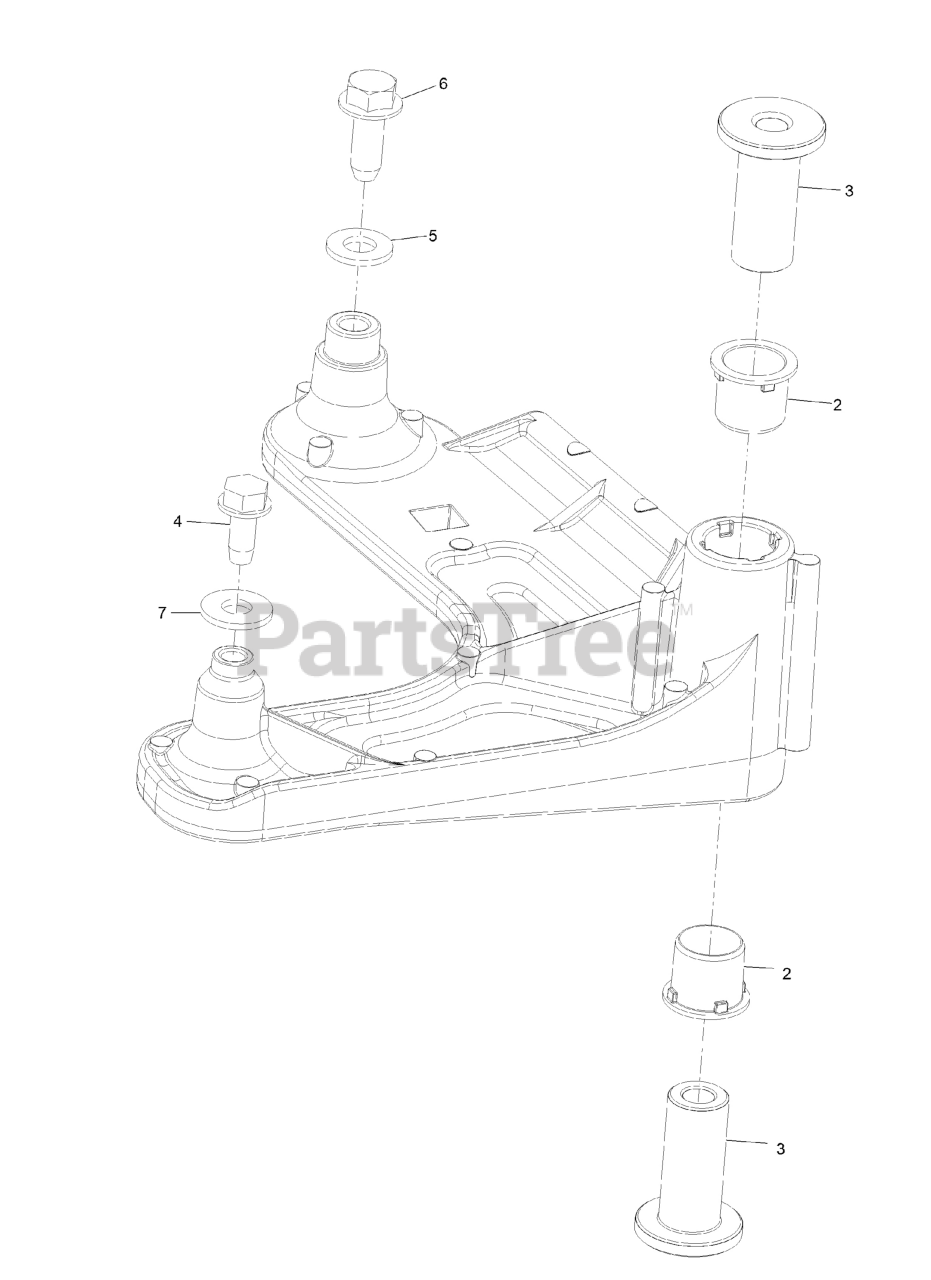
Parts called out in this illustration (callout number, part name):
2	BUSHING, IGUS
3	Spacer, Idler Pivot
4	SCREW-THD ROLL, HWH
5	WASHER-FLAT
6	SCREW-FORMING, THREAD
7	WASHER-FLAT
